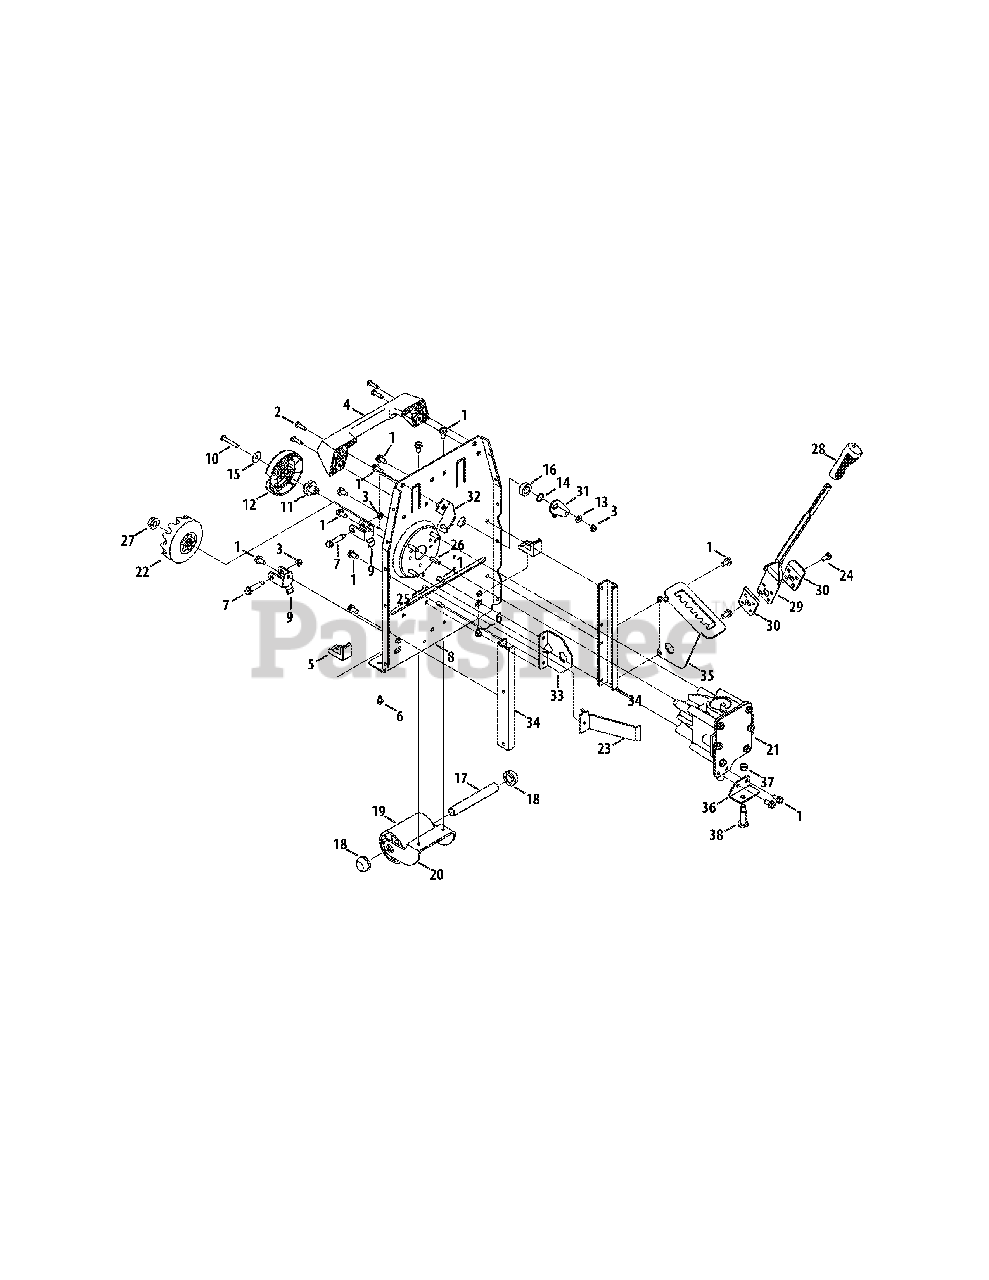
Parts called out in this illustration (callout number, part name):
1	Hex Washer Screw, 5/16-18 x .750
2	Self-tapping Screw, 1/4-20 x 1.00
3	Flange Lock Nut, 1/4-20
4	Rear Handle
5	Bumper Pad
6	Shoulder Screw, 1/4-20 x 0.50
7	Shoulder Screw,, 1/4-20 x .375 x 1.355
8	Frame Mounting Bracket
9	Support Bracket
10	Hex Cap Screw, 1/4-20 x 1.75
11	Clutch Link Shaft
12	Idler Clutch
13	Bell Washer, .265 x .75 x .062
14	Wave Washer, .65 ID x .855 x .010
15	Flat Washer, .265 x 1.0 x .030
16	Hex Flange Bearing 5/8 PM
17	Roller Shaft, .75 x 5.440
18	Push Cap, 3/4
19	Deck Roller
20	Roller Bracket
22	Clutch Assembly
24	Hex Cap Screw, 5/16-24 x .750
25	Hex Washer Screw, 1/4-20 x .500
26	Self-Tapping Screw, 5/16-18 x 1.00
27	Flange Lock Nut, 1/2-13
28	Grip Handle, 1/2
29	Deck Height Lever
30	Pivot Lever Bracket
31	Deck Engagement Bracket
32	Deck Cable Bracket
33	Shift Lift Bracket
34	Deck Channel Bracket
37	Hex Lock Nut, 3/8-16, Centerlock
38	Shoulder Screw, .500 x 1.25 x 3/8-16
